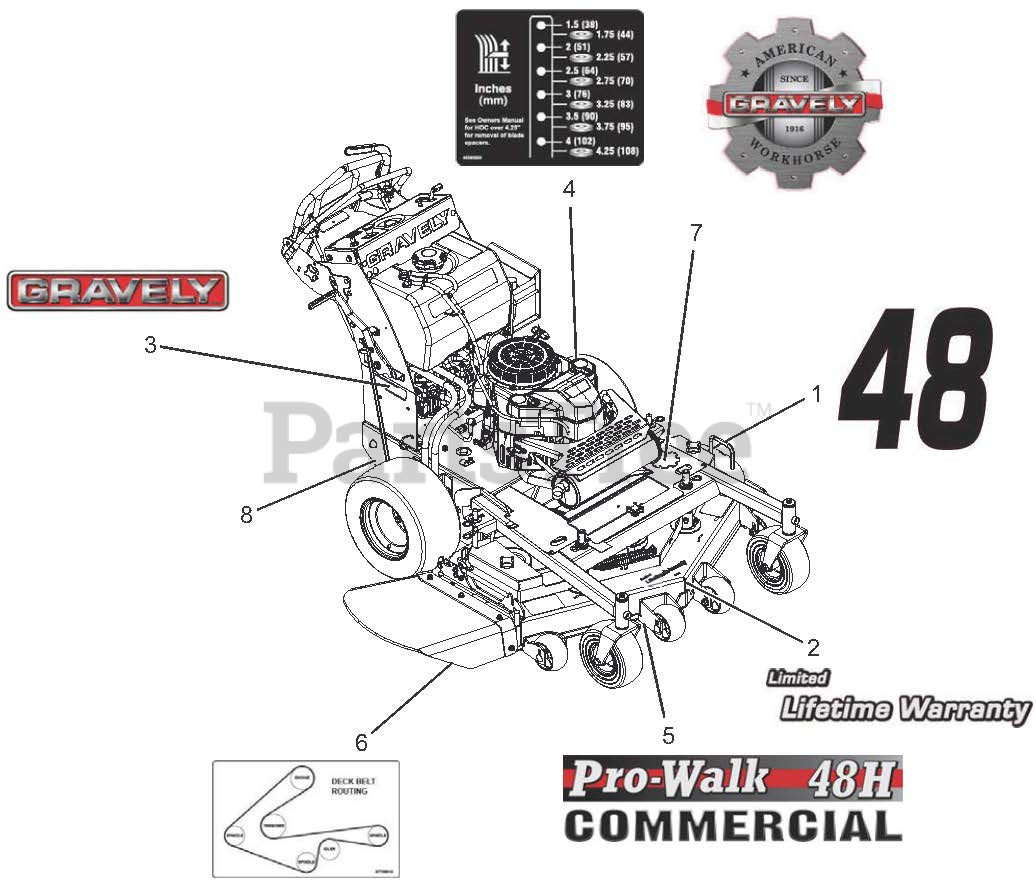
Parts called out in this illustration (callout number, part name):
1	DECAL, 48"
2	DECAL, LIMITED LIFETIME WARRANTY REV
3	DECAL, 6.5" GRAVELY LOGO
4	DECAL, PRO WALK HOC A
5	DECAL, PROWALK 48H
6	DECAL, BELT ROUTING 48/52 REV
7	DECAL, GRAVELY HERITAGE-LARGE
8	DECAL, PUMP BELT ROUTING
